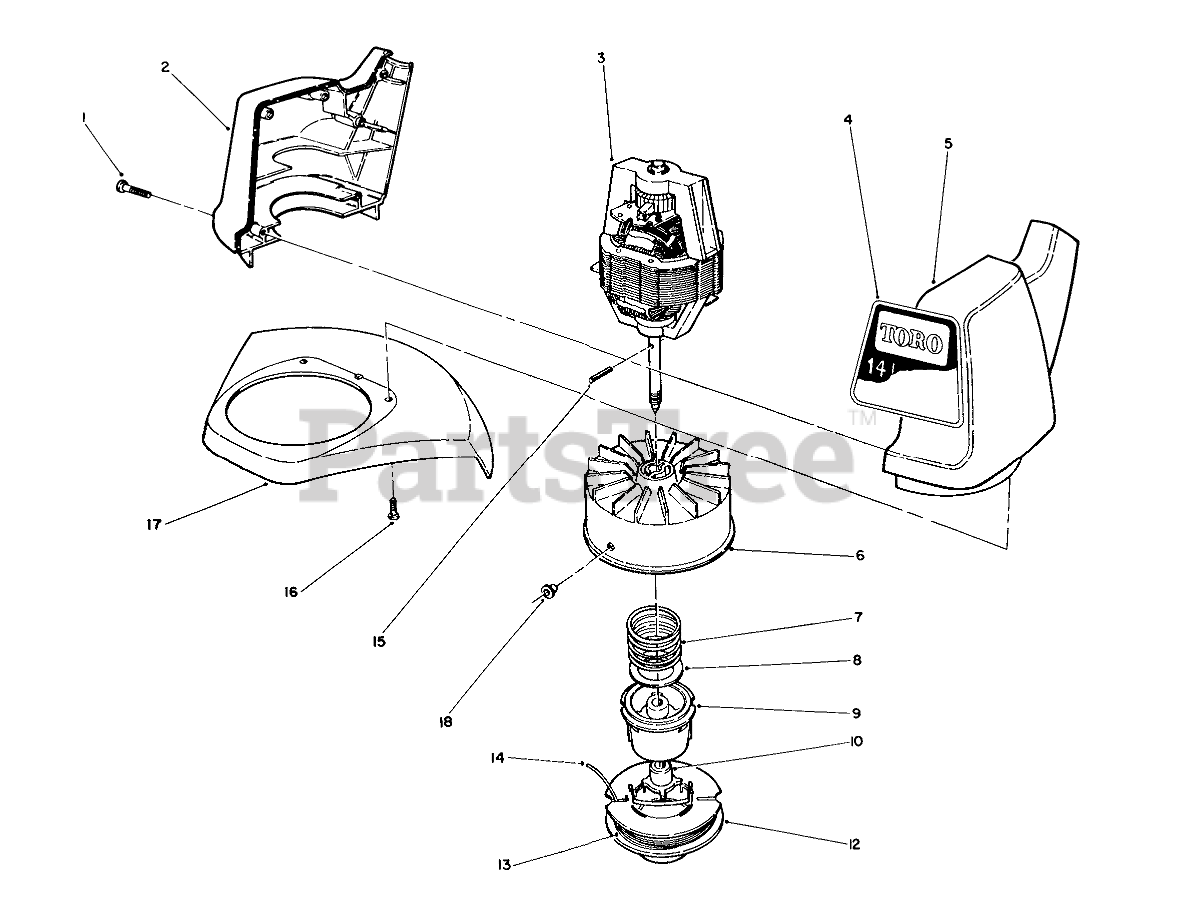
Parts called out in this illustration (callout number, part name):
1	SCREW-PPH
2	RH HOUSING, 14" TRIMMER
3	MOTOR, 1410 TRIMMER
4	1410 DECAL
5	LH HOUSING, 14" TRIMMER
6	Drum & Eyelet Assembly
7	SPRING COMPRESSION
8	WASHER-FLAT
9	SPOOL CORE
10	DRIVER
12	SPOOL CAP
13	Cutting Line (50 .065" Dia.)
14	50-, .065" Dia. Cutting Line In Coil
15	COIL PIN
16	SCREW-PPH
17	Shield Assembly
18	Eyelet
